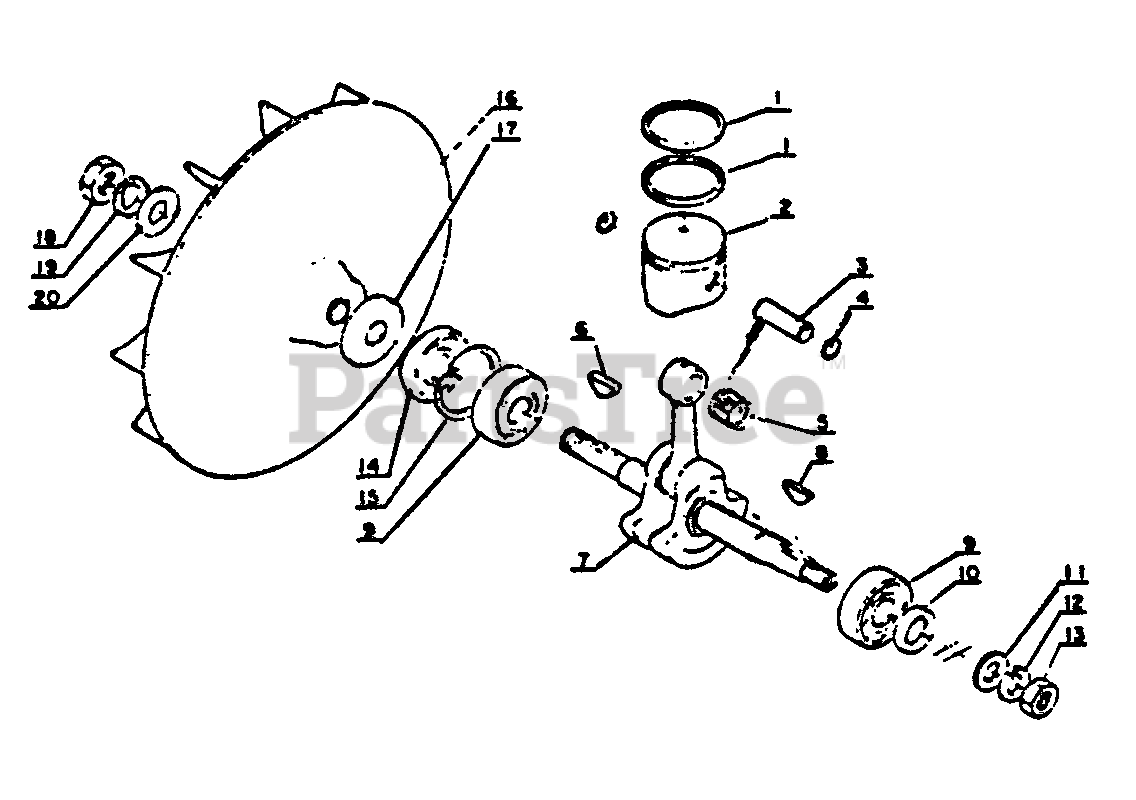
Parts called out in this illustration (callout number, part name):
1	RING, PISTON
2	PISTON
3	PIN, PISTON
4	RING, RETAINING
5	BEARING, NEEDLE
7	CRANKSHAFT ASSY
9	BEARING, BALL - 6201
10	SEAL, OIL
12	LOCKWASHER - 8
14	SEAL, OIL
15	RING, RETAINING - 32
16	FAN
17	WASHER, THRUST
18	NUT - 10
19	LOCKWASHER - 10
20	WASHER - 10
